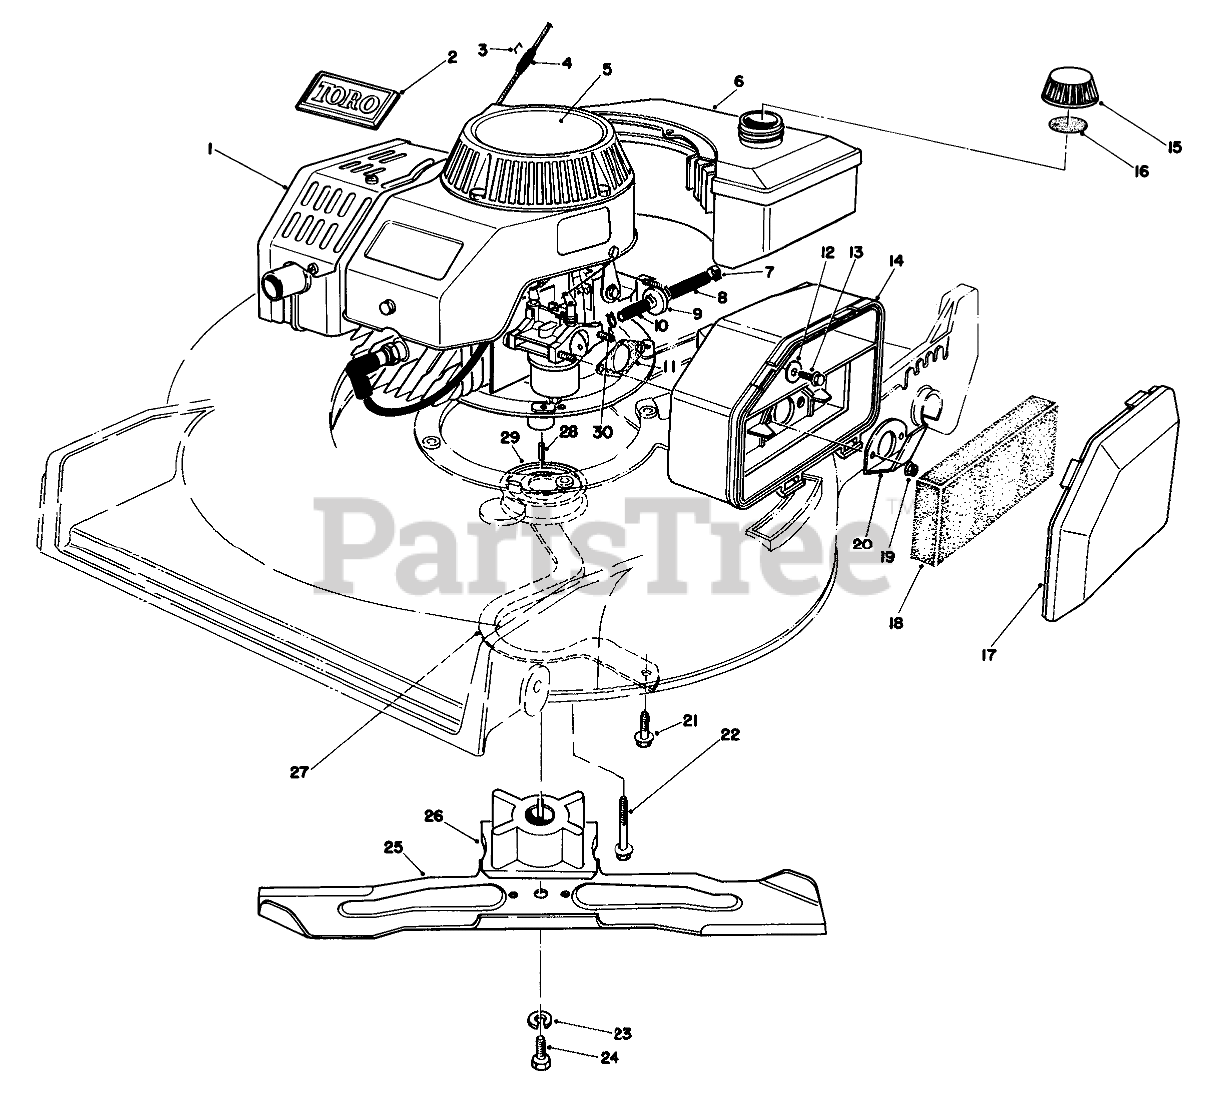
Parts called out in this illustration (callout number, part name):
1	Engine
2	TORO LOGO PLT
3	Staple
4	STOP-ROPE
5	DECAL
6	Gas Tank Assembly
7	CLAMP-FUEL LINE
8	HOSE-FUEL
9	FILTER-FUEL
10	HOSE-FUEL
11	GASKET-AIR CLEANER
12	WASHER-FLAT
13	SCREW-HH
14	AIR CLEANER
15	Gas Cap Assembly (Incl. Ref. #16)
16	GAS CAP GASKET
17	AIR CLEANER COVER
18	FILTER
19	NUT-LOCK
20	SPIT BACK DEFLECTOR
21	Screw
22	SCREW-HHF
23	WASHER-LOCK
24	SCREW-BLADE
25	BLADE-21in
26	Retainer Blade
27	BELT GUIDE
28	KEY-SQUARE
29	PULLEY-DRIVER
30	CLAMP-HOSE
